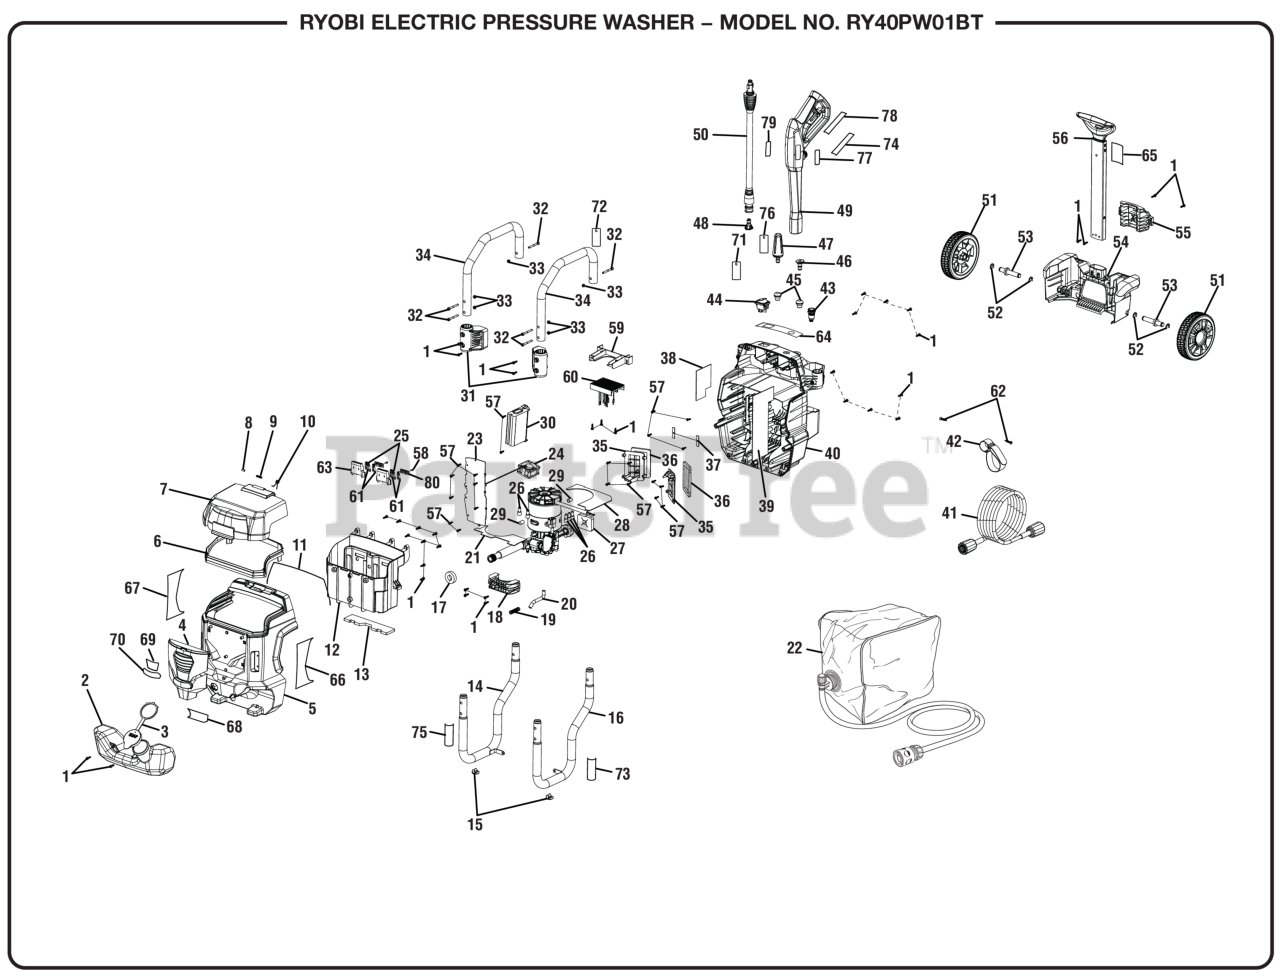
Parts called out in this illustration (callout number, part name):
1	Screw (M4.2 x 15 mm, Phillips Hd. S.T.)
2	Soap Tank
3	Detergent Tank Cap
4	Decorative Cover
5	Front Housing
6	Battery Cover Rubber Seal
7	Battery Cover
8	Battery Door Axle
9	Compression Spring
10	Battery Cover Spring
11	Front Housing Rubber Seal
12	Battery Tray
13	Battery Foam Tray Waterproof Cover
14	Lower Frame (Right)
15	Rubber Foot
16	Lower Frame (Left)
17	Outlet Tube Cover Foam
18	Pump Bracket
19	Detergent Tank Spring (Compression Spring
20	Siphon Tube
21	Air Front Sheet
22	Water Bag Assembly
23	Air Way Cover
24	Control Board Cooling Fan
25	STAMPING I BATTERY CONTACT PLATE TERMINA
26	Close-End Connector
27	Inlet Tube Cover
28	Air-Separation Sheet
29	Shock Absorbing Bushing
30	40V DC Controller
31	Frame Holder
32	Bolt (M5 x 42 mm)
33	Lock Nut (M5 x 0.8 mm)
35	Corner Cover
36	Cover Sealing Foam
37	Metal Plate
38	Water Block Sheet (Right)
39	Water Block Sheet (Left)
40	Rear Housing
41	Hose (25 ft.) [PS141913]
42	Hook and Loop Strap
43	Boost Button
44	Power Switch
45	Nozzle Grommet
46	15 Deg Nozzle
47	Turbo Nozzle
48	Soap Nozzle (Blue)
49	Trigger Handle Assembly
50	Spray Wand Assembly
51	6 in. Wheel
52	Retaining Ring
53	Wheel Axle (D12.7 x 76)
54	Wheel Base Bracket
55	Holder Cover
56	Retractable Handle Assembly
57	SCREW, ST3.5X12, PAN HEAD
58	Screw (M3 x 8 mm, Pan Hd., Pan Hd)
59	Control Board Bracket
60	Control Board Assembly
61	Contact Plate Terminal
62	Screw (M4 x 25.4 mm, Flat Hd. S.T.)
63	Battery Contact Holder
64	On/Off Label
65	Starting Instructions Label
66	Warning Label (Eng)
67	Warning Label (Fr)
68	Performance Label
69	40V Label
70	Brushless Logo Label
71	Battery Notice Label
72	Spanish Hangtag
73	Detergent Label
74	Trigger Handle Data Label
75	Inquires Label (Ryobi)
76	Nozzle Hangtag (PS141913)
77	Trigger Handle Warning Label (English)
78	Trigger Handle Warning Label (French/Spanish)
79	Trigger Handle Label (Logo Label)
80	Battery Cover Connector
